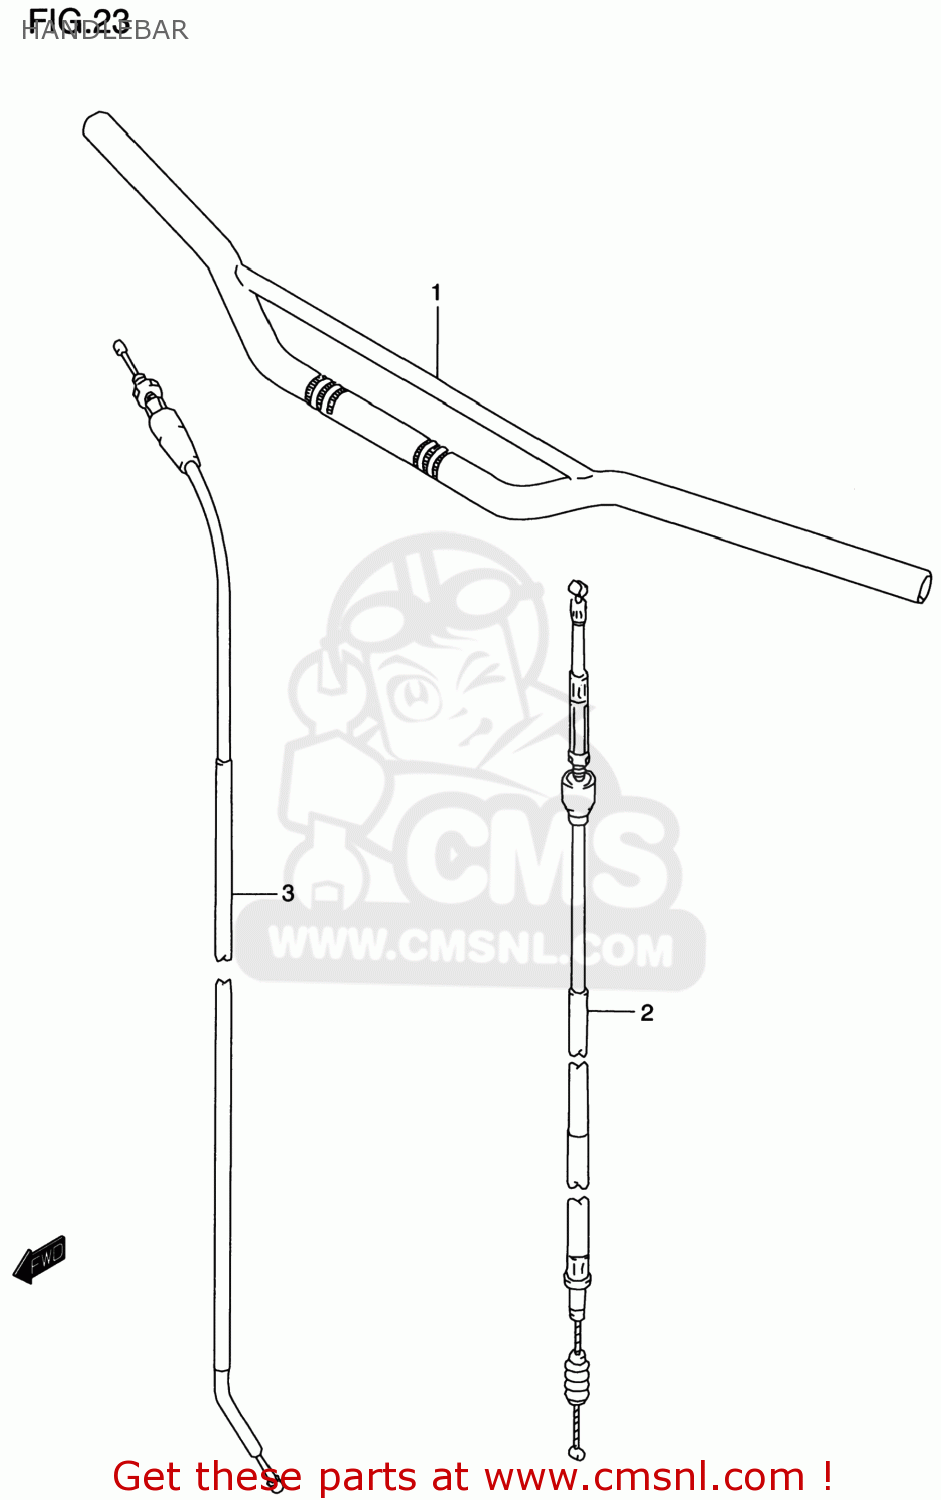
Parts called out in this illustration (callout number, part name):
1	HANDLEBAR(SILVER)
2	CABLE ASSY,CLUTCH
3	CABLE ASSY,THROTTLE
